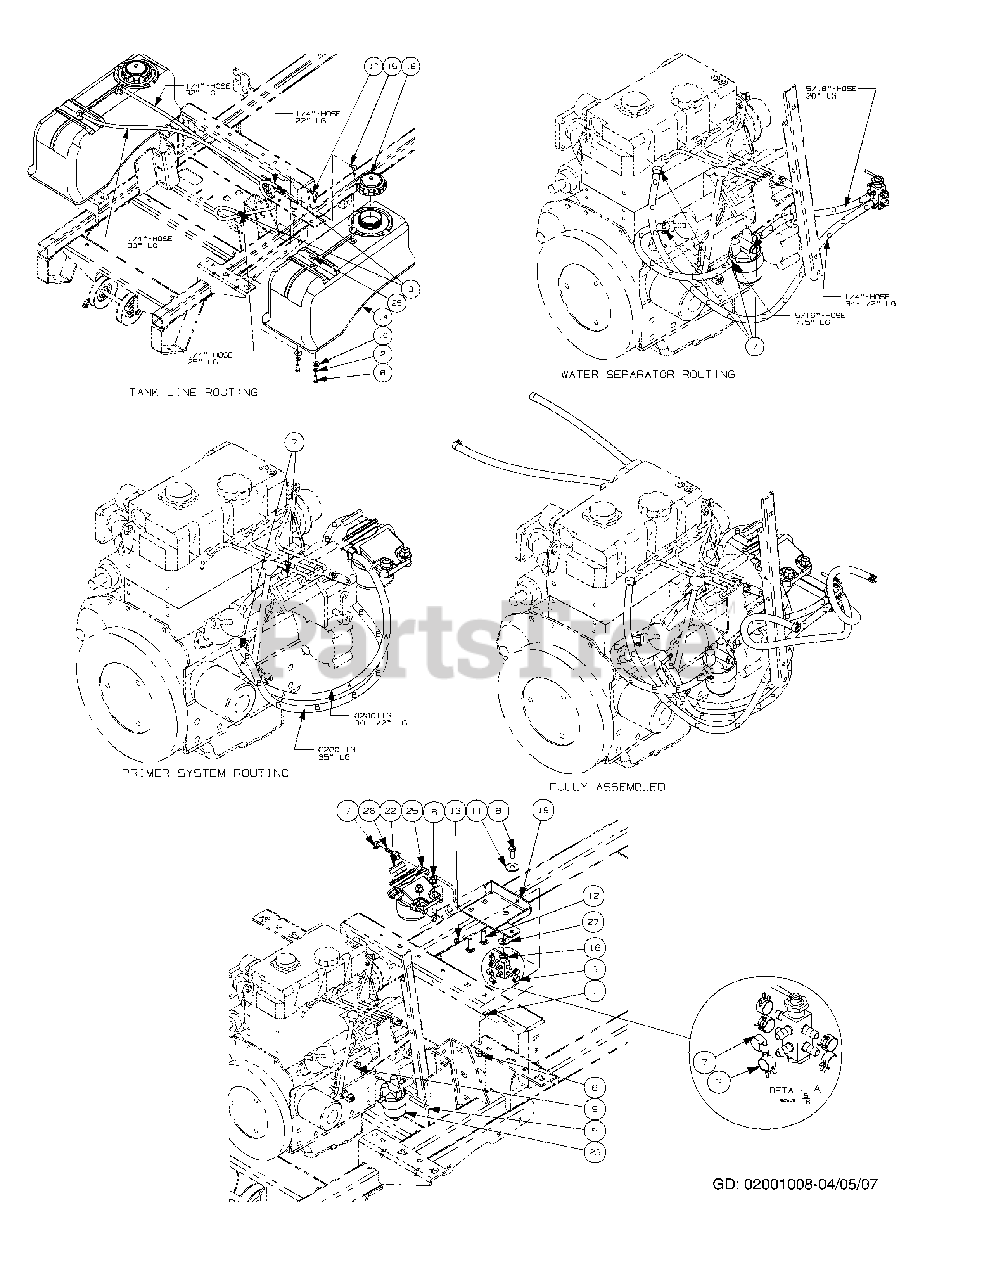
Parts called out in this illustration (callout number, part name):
1	Hex Cap Screw, 1/4-20 x 1/2
2	Lock Washer, 3/8
3	Clamp, Union
4	Cable Tie
5	Hex Cap Screw, 5/16-18 x 2.00
6	Hex Nut, 3/8-16, Lock Flange
7	Hose Clamp
8	Hex, Cap Screw, 3/8-16, .88
9	Nut, Lock, HexFlange, 5/16-18
10	Flat Washer, .406 ID, 1.0 OD, .105
11	Washer, 1.25 x .411 x .100
12	Carriage Screw, 3/8-16 x 1.25
13	Lock Nut, 1/4-20
14	Fuel Tank
15	Fuel Fitting, Return
16	Shut Off Fuel Valve
17	Fuel Fitting, Pickup
19	Fuel Filter Mounting Bracket
20	1/4" Hose, Carb BioDiesel (162.50 inches)
21	5/16" Hose, Carb BioDiesel (93.00 inches)
22	Fuel Strainer
23	Water Filter
24	Fuel Tank Grommet
25	Adaptor, M14 x 1.5 ORB x 4JIC MA
26	Adaptor, 4JIC FE x 1/4 Barb
27	Lock Washer
